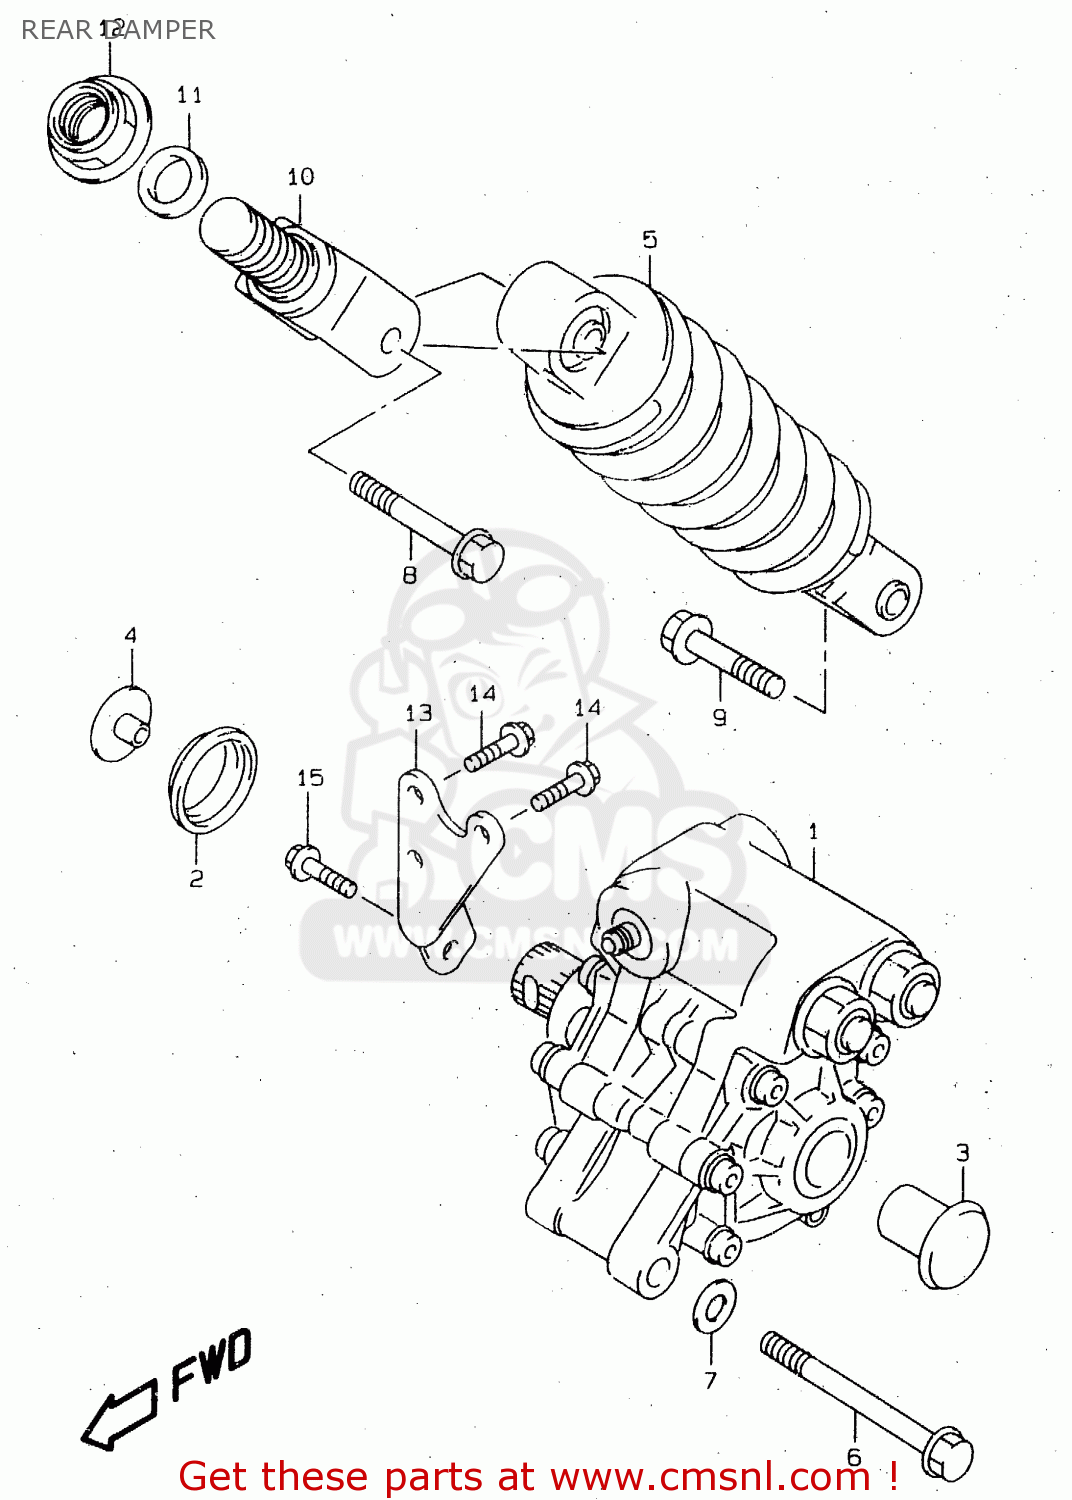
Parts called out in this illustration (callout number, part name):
1	DAMPER ASSEMBLY,REAR
2	CAP
3	CAP
4	CAP(OD:19.5)
5	UNIT ASSY,RR SPRING
6	BOLT
7	WASHER
8	BOLT(10X52)
9	BOLT(10X48)
10	BRACKET,RR SHOCK ABSORBER UPR
11	SPACER,BRACKET(20.4X29X7.2)
12	NUT
13	BRACKET,RR DAMPER
14	BOLT
15	BOLT
